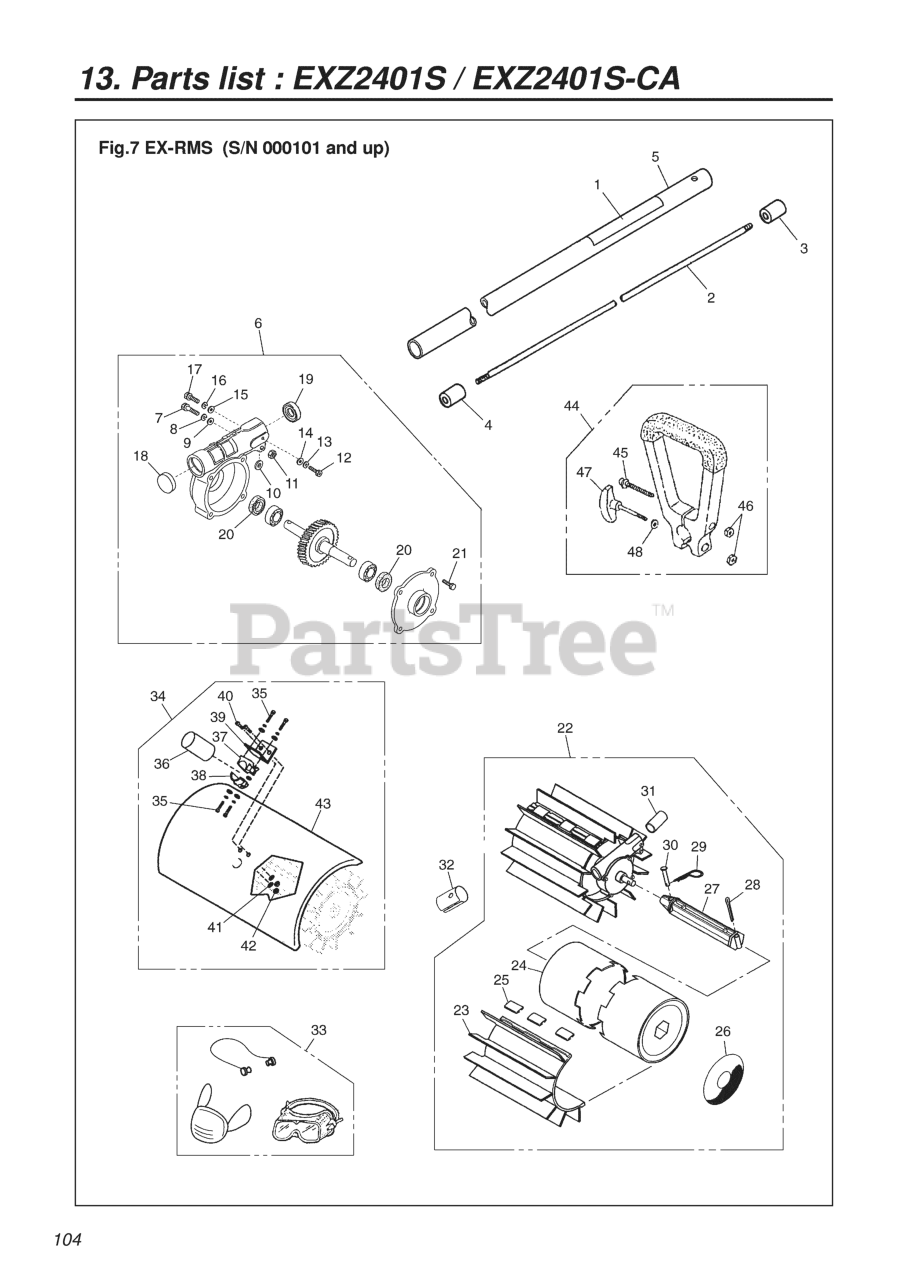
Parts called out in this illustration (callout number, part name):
1	PIPE COMP
2	SHAFT
3	SHAFT-JOINT
4	SPACER
5	PLATE-NAME
7	BOLT, M6 x 30
8	SPRING WASHER
9	WASHER, FLAT
10	WASHER, FLAT
11	NUT, M6 X 5
12	BOLT, M5 x 12
13	WASHER, SPRING M4 x 1.3
16	WASHER, SPRING M4 x 1.3
17	SCREW
18	PLUG, HOUSING
21	SCREW
22	SWEEPER ASSY
25	CLIP, BELT
26	LABEL, REDMAX
27	DRUM AXLE
28	PIN, COTTER
29	PIN, HITCH
30	CLEVIS PIN
31	PROTECTOR, TUBE
33	SAFETY KIT
34	DEBRIS SHIELD ASSEMBLY
37	BRACKET, HANDLE
38	CAP, LOWER
39	BRACKET, SHIELD
44	HANDLE ASSY
